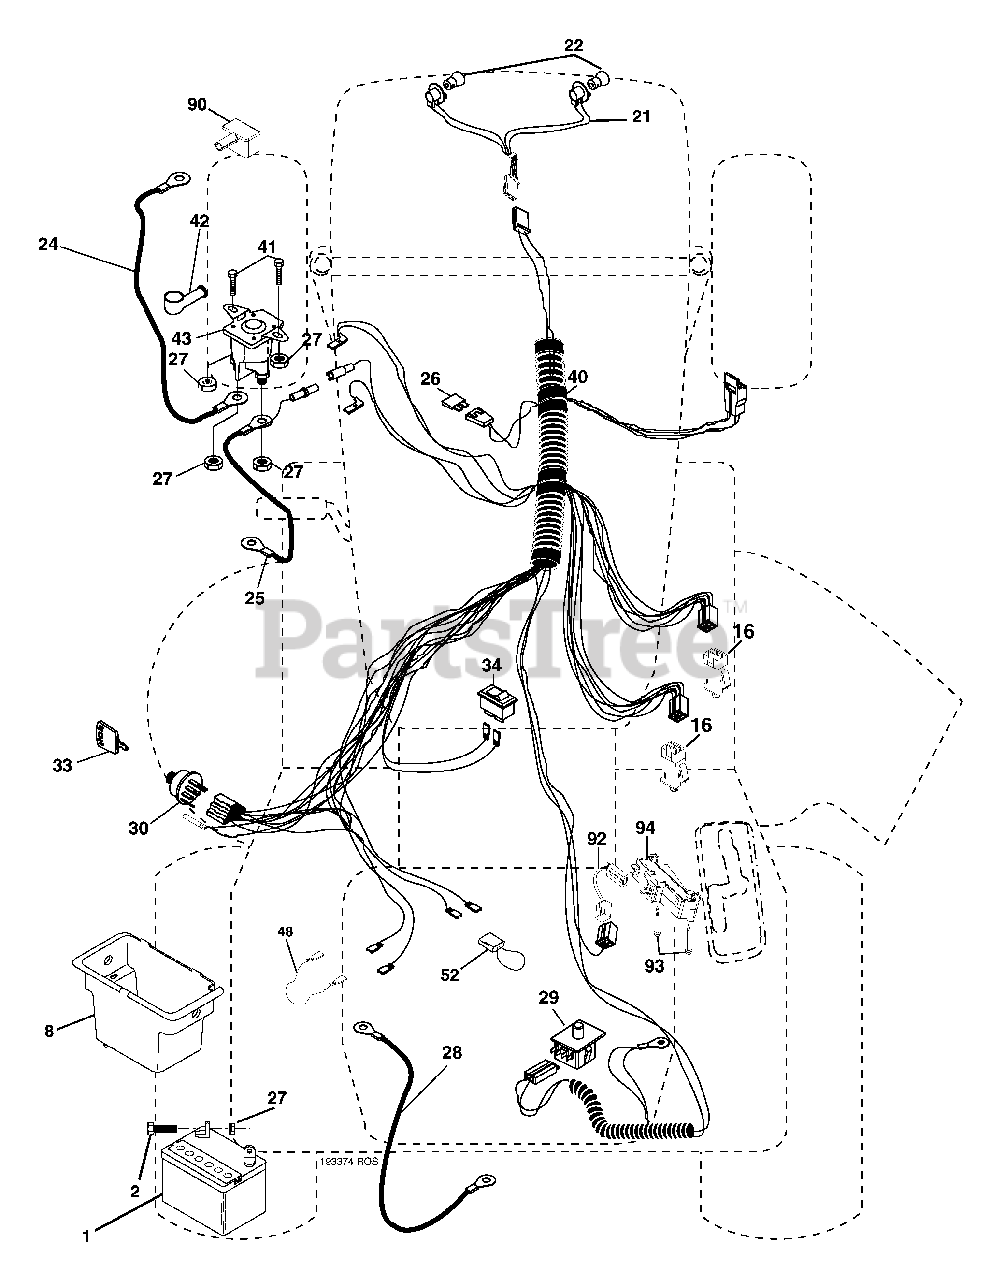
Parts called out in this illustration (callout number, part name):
1	Battery
2	Bolt Hex Hd 1/4-20 unc x 3/4
8	Box Battery
16	Switch Interlock
21	Harness Socket Light
22	Bulb, Light # 1156
24	Cable Battery
25	Cable Battery 6 Ga. Red w/16 wire 44"
26	Fuse
27	Nut Keps Hex 1/4-20 unc
28	Cable Ground 12" Blk 6 Ga.
29	Switch Seat
30	Switch Ign
33	Key Ign Molded Generic
34	Switch Light/Reset
40	Harness Ign
41	Bolt Fin Hex 1/4-20 unc x 1/2
42	Cover Terminal Red
43	Solenoid
48	Adapter Ammeter
52	Protection Loop
90	Cover Terminal
92	Harness Pigtail Reverse Switch
93	Screw Plastite 10-14 x 2.0
94	Module Revers ROS
